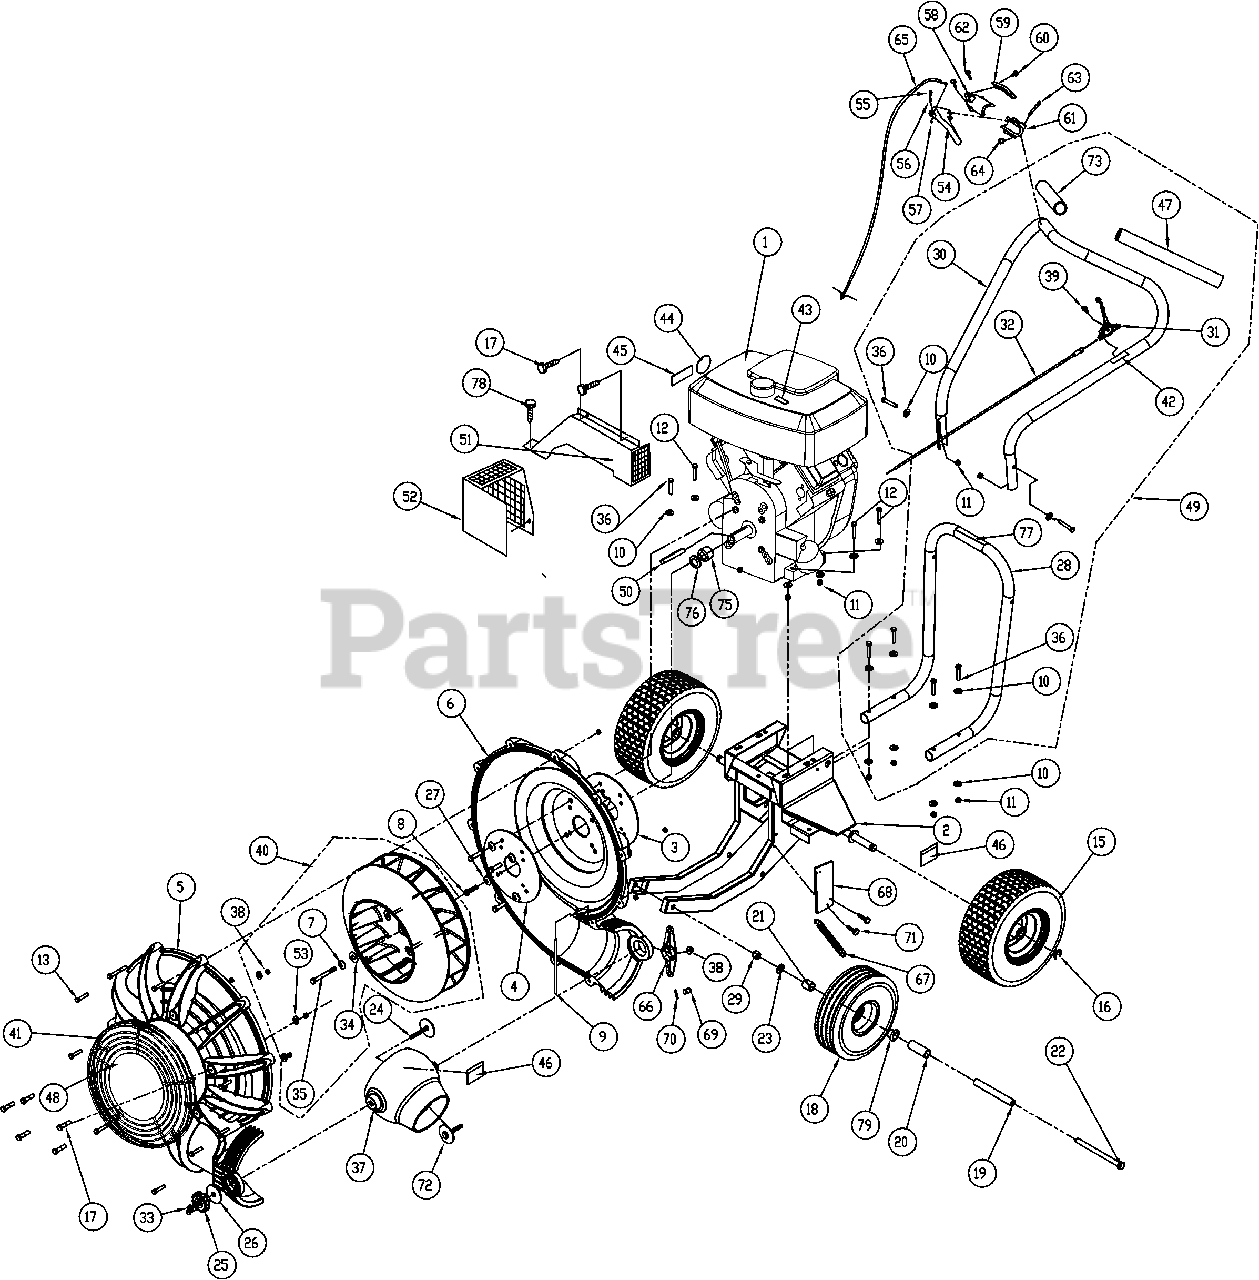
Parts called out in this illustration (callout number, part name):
1	ENGINE 18 VANGUARD
2	BASE ENGINE WA
3	SPACER RING ENGINE
4	PLATE REINFORCE HOUSING
5	HOUSING FRONT MOLDED
6	HOUSING BACK MOLDED
7	WASHER LOCK 3/8 TWISTED TOOTH
8	SCREW CAP 3/8-16X1 1/2 ZP
9	ROD HAND STOP
10	WASHER 5/16 FLATWASHER Z/P
11	NYLON INSERT LOCKNUT 5/16-18
12	SCREWCAP 5/16-18 X 1.75 ZP
13	SCREWCAP 1/4-20 x 1 1/2
14	NUT FLANGE 1/4-20
15	WHEEL & TIRE 13" X 5" PNEUMATIC
16	RING RETAINING 3/4
17	SCREW SM 1/4 x 1 DRILL PT.
18	WHEEL ASSY 10 " PNEUMATIC
19	SPACER FRONT AXLE
20	SPACER LH WHEEL
21	SPACER RH WHEEL
22	SCREWCAP 1/2-13 x 7"
23	WASHER FLAT 1/2" SAE
24	WASHER W/BOLT WA
25	KNOB 3/8-16 SOLID HUB
26	WASHER 2.25 OD x .515 ID x .134 ZP
27	WASHER LOCK 3/8 S/T MED
28	HANDLE LOWER
29	NYLON INSERT LOCKNUT 1/2-13
30	HANDLE UPPER
31	CONTROL THROTTLE
32	CABLE THROTTLE CONTROL
33	NUT LOCK 3/8-16 LT WT THIN ZP
34	WASHER 1.5 O.D.X 0.453 X 0.5
35	SCREWCAP 3/8 - 24 X 4 1/2" GR. 8 (33-38 ft. lbs)
36	SCREWCAP 5/16"-18 X 2" ZP
37	DIRECTOR CONE 6"
38	NUT LOCK 1/4" - 20 HEX ZP
39	SCREW SM #10-24X1/2" DRILL POINT
40	IMPELLER ASSEMBLY 17"
41	GRILL FRONT BLOWER
42	LABEL THROTTLE CONTROL
43	LABEL HOT ENGINE
44	LABEL READ
45	LABEL EAR EYE BREATHING
46	LABEL DANGER FLYING DEBRIS
47	GRIP 1-1/4" ID x 13"
48	LABEL FORCE
49	HANDLE ASSY UPPER
50	KEY 1/4" SQ X 2.25
51	GUARD MANIFOLD
52	GUARD MUFFLER
53	WASHER FLAT 1/4
54	HANDLE DIVERTER FORCE
55	PIN LATCH DIVERTER
56	SPRING COMPRESSION 0.281 X 0.88
57	RING RETAINING .122 DIA
58	SADDLE UPPER DIVERTER
59	PLATE LOCK DIVERTER
60	SCREW PLASTITE #6-19 X 5/8"
61	SADDLE LOWER DIVERTER
62	SCREW PLASTITE #10-14 X 1"
63	PIN PIVOT DIVERTER CONTROL
64	RING RETAINING 5/16
65	CABLE ASSY
66	DIVERTER PIVOT ADAPTOR
67	SPRING EXTENSION 0.468 X 5.25
68	BRACKET DIVERTER FORCE
69	PIN CLEVIS 1/4 X 3/4
70	.051 X 3/4" HITCH PIN CLIP
71	SCREW TCS #12-24 X 5/8" TYPE 1
72	ADAPTOR MOUNT WA
73	GRIP 1-1/4" ID x 9.5" LONG
75	SPACER 1" ID X 2" OD X 0.890 TK
76	SPACER 1" ID X 2" OD X 0.265 TK
77	VIBRATION LABEL
78	SCREW SELF TAP 1/4" - 20 X 5/8"
79	FORCE WHEEL BEARING .751 ID
